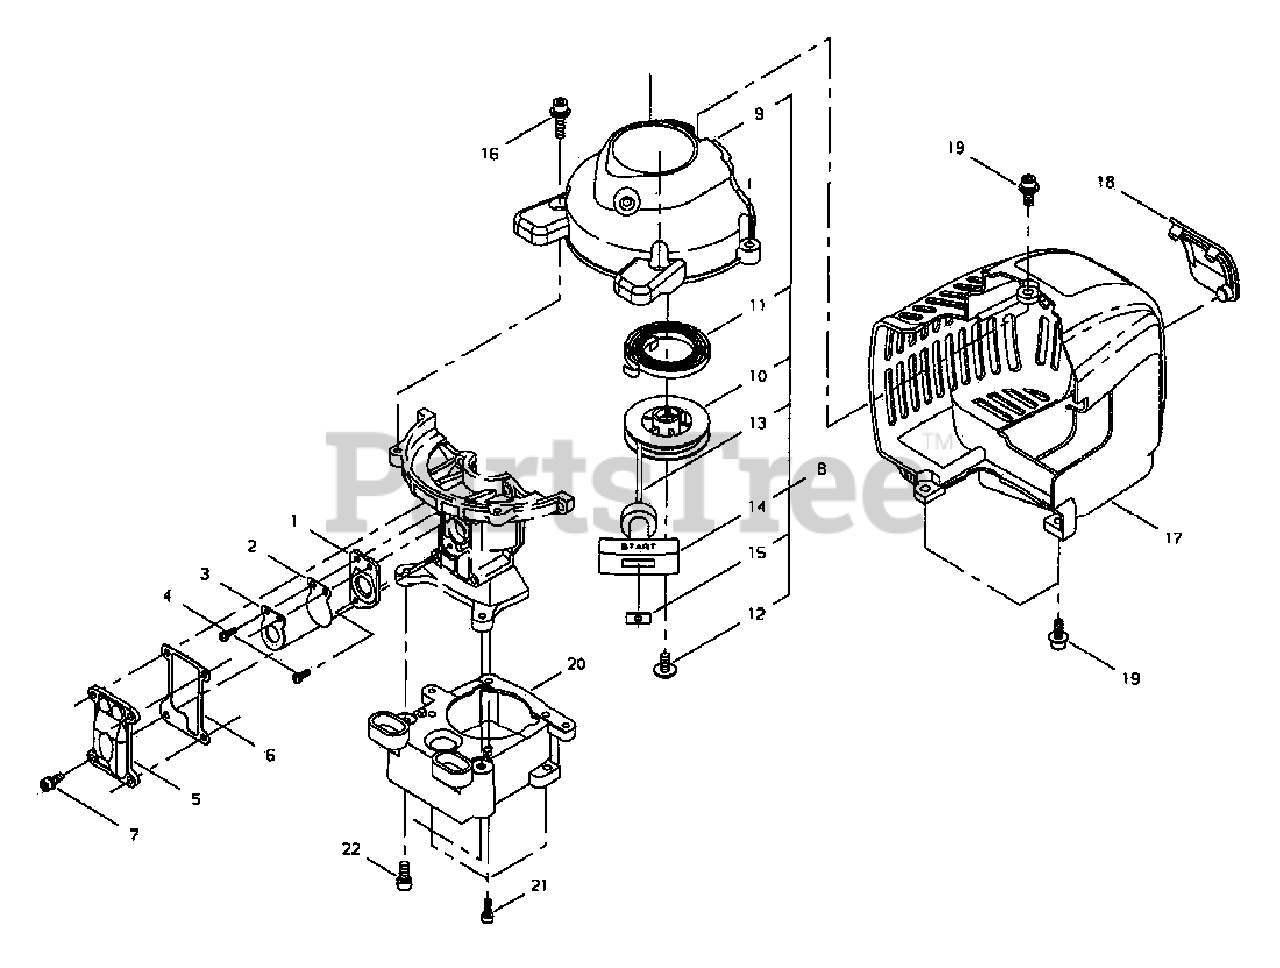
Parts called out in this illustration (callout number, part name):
1	PLATE, REED BACKING
2	VALVE, REED
3	STOP, REED VALVE
4	SCREW - 3X10
5	COVER, REED VALVE
6	GASKET, REED VALVE
7	SCREW - 4X12
8	STARTER ASSY
9	CASE, STARTER
10	REEL, ROPE
11	SPRING, REWIND
12	SCREW - 5
13	ROPE, STARTER
14	GRIP, STARTER
15	RETAINER, ROPE
16	SCREW - 5X20
17	COVER, ENGINE
18	GROMMET
19	SCREW - 5X14
20	ADAPTOR, GEAR CASE
21	SCREW - 4X12
22	SCREW - 5X12
